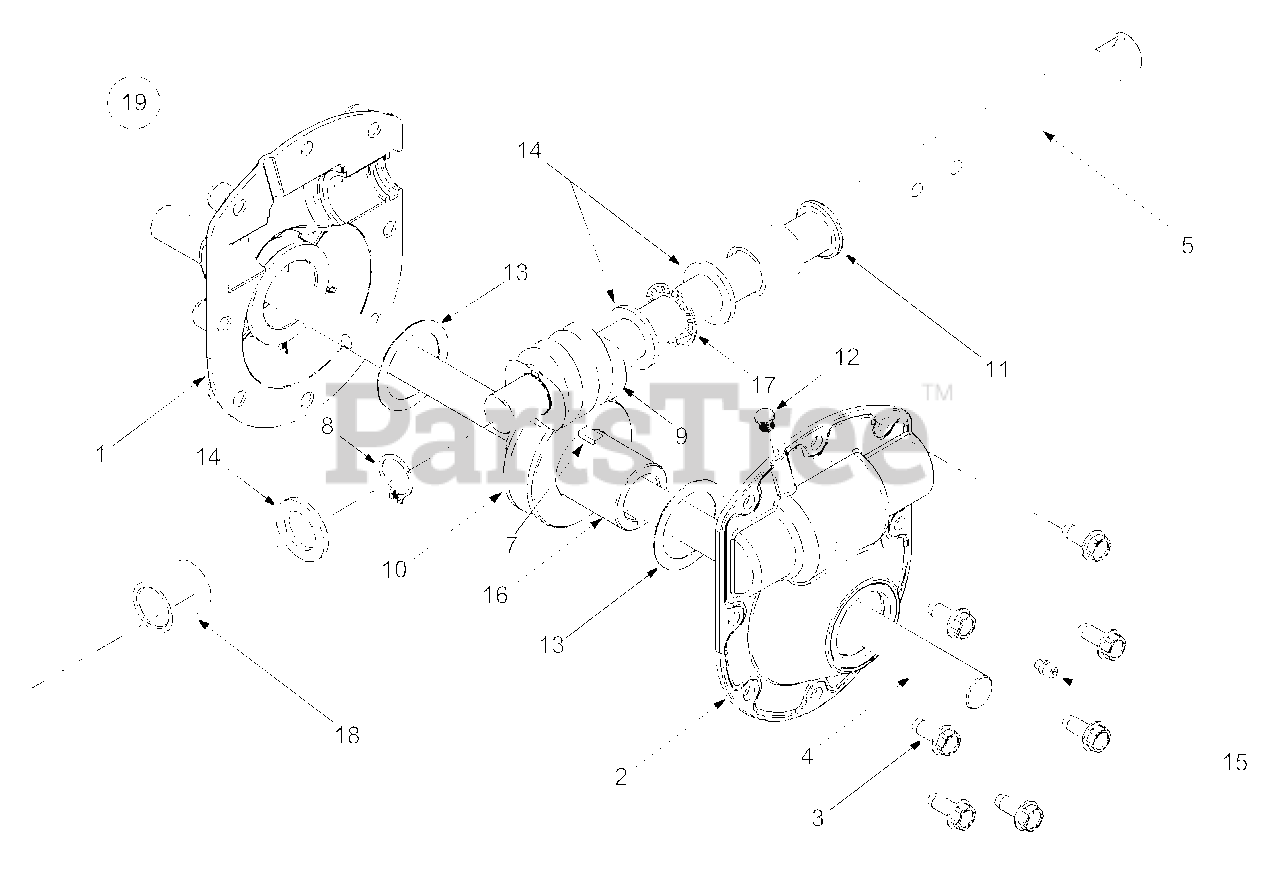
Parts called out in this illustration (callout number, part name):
1	Housing Assembly, RH
2	Housing Assembly, LH
3	Screw, 5/16-18 x 0.75
4	Axle, Auger
5	Shaft, Auger Drive
6	Key, Hi Pro, 3/16 x 3/4
7	#91 Woodruff Key 1/4 x 3/4
8	Snap Ring .875 Dia.
9	Gear, Worm, Double Thread LH
10	Gear, Worm, LH
11	Seal, Oil .875 ID
12	Plug, 1/4 x .437
13	Washer, Flat, 1.52 x 2.0
14	Washer, Flat, .88 x 1.38
15	Lube Fitting, 3/16 Drive
16	Shaft, Worm Gear
17	Bearing, Thrust .877
18	Sleeve Bearing, .877 x .125 x 1.11
19	Auger Gearbox Assembly Complete
